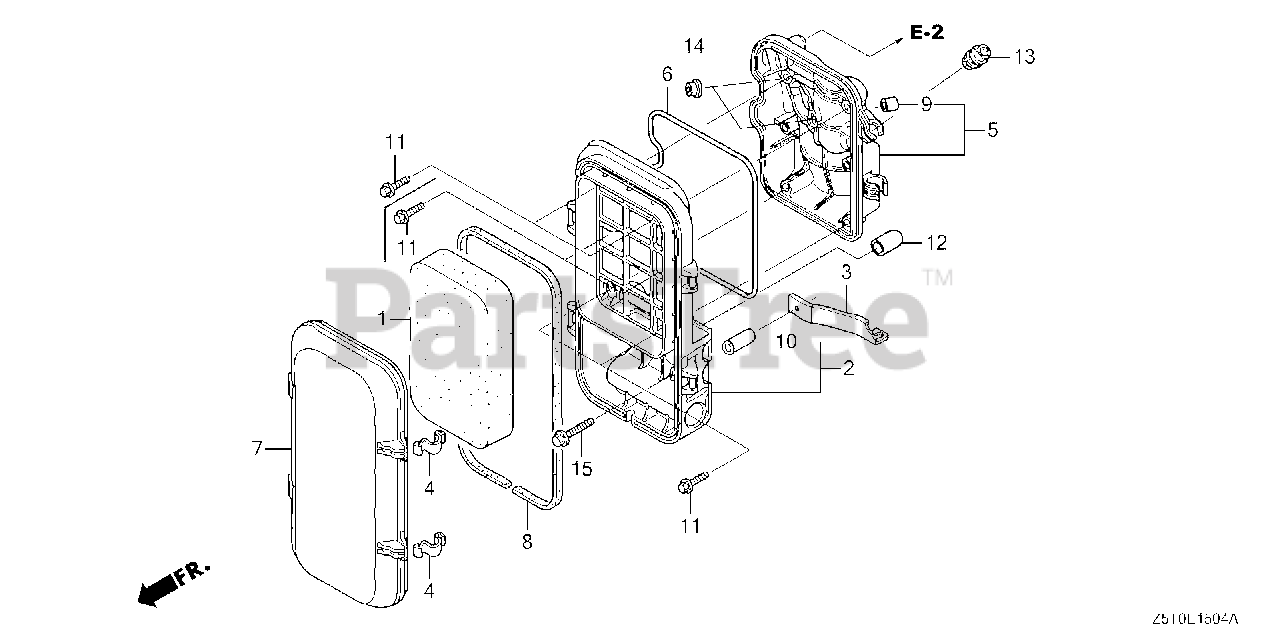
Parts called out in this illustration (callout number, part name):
1	ELEMENT, AIR CLEANER
2	HOUSING, AIR CLEANER
3	STAY, AIR CLEANER
4	SPRING, AIR CLEANER HOUSING LID
5	BASE, AIR CLEANER
6	SEAL, AIR CLEANER HOUSING
7	COVER, AIR CLEANER
8	SEAL, AIR CLEANER COVER
9	COLLAR, AIR CLEANER
10	COLLAR, AIR CLEANER
11	BOLT, FLANGE (5X18)
12	CAP, SEALING
13	RUBBER, FUEL (9X15X20)
14	NUT, FLANGE (6MM)
15	BOLT, FLANGE (6X32)
